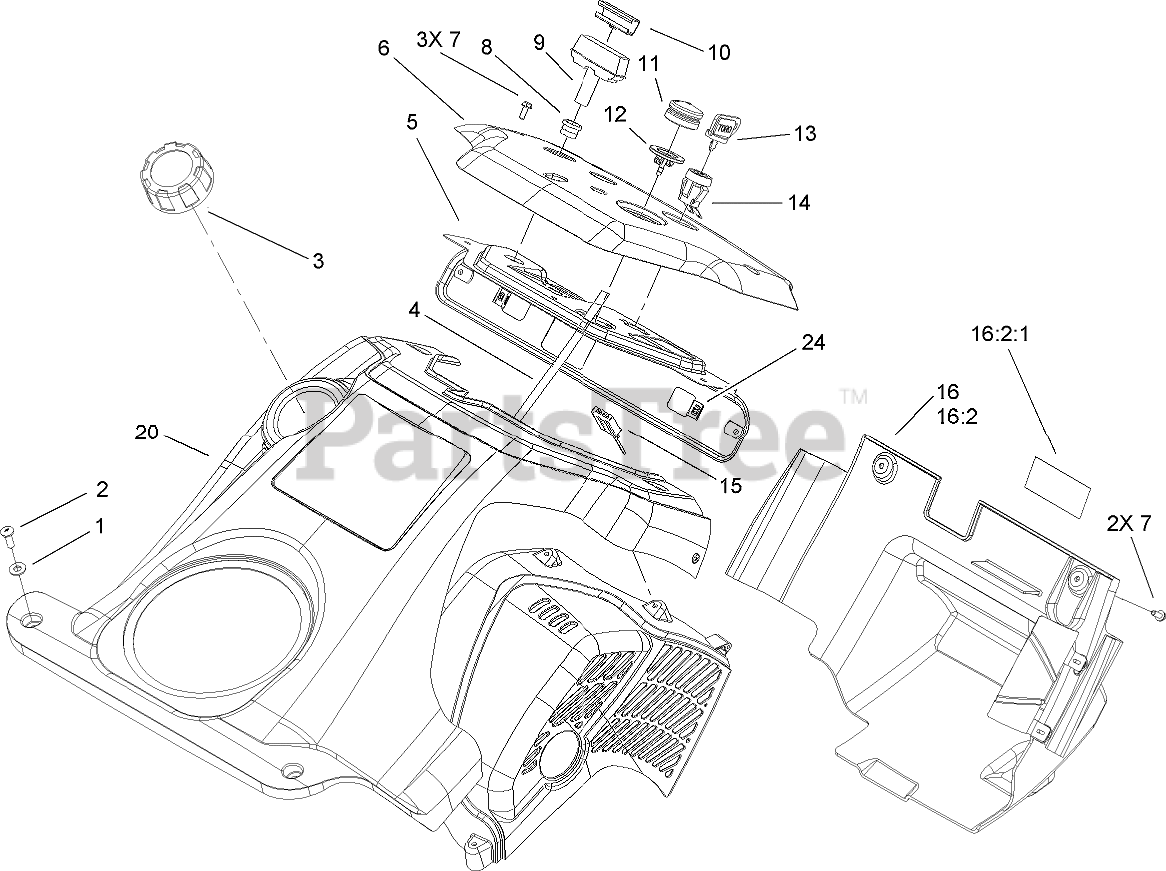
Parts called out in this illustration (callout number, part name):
1	WASHER-FLAT
2	SCREW-PPH
3	GAS CAP ASM
4	HOSE-PRIMER
5	PANEL-SUPPORT, CONTROL
6	PANEL-CONTROL
7	SCREW-HWH
8	GUIDE-ROPE, STARTER
9	HANDLE-START
10	CLIP-STARTER
11	BULB-PRIMER
12	BODY-PRIMER
13	KEY-IGNITION
14	SWITCH
15	CONNECTOR-BODY
16	LOWER SHROUD AND BAFFLE ASM
16:2	SHROUD-LOWER
16:2:1	DECAL
20	UPPER SHROUD ASM
24	NUT-SPEED
